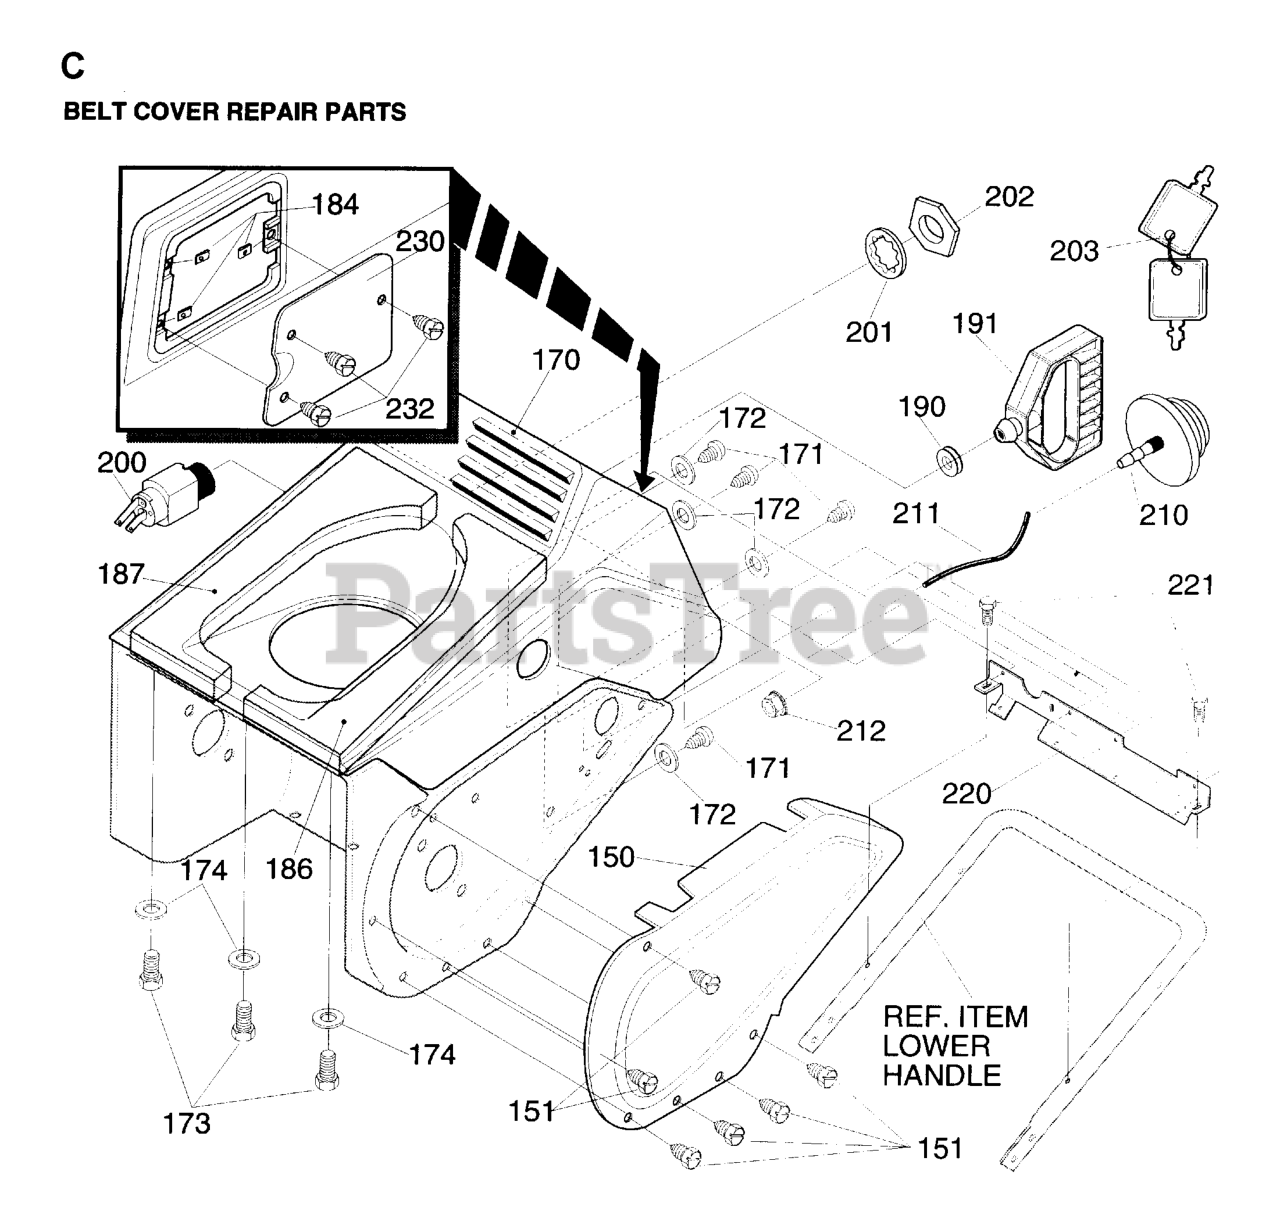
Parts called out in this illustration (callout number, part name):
170	COVER
186	FOAM RUBBER NLA
187	FOAM RUBBER NLA
191	STARTER HANDLE
200	IGNITION SWITCH
